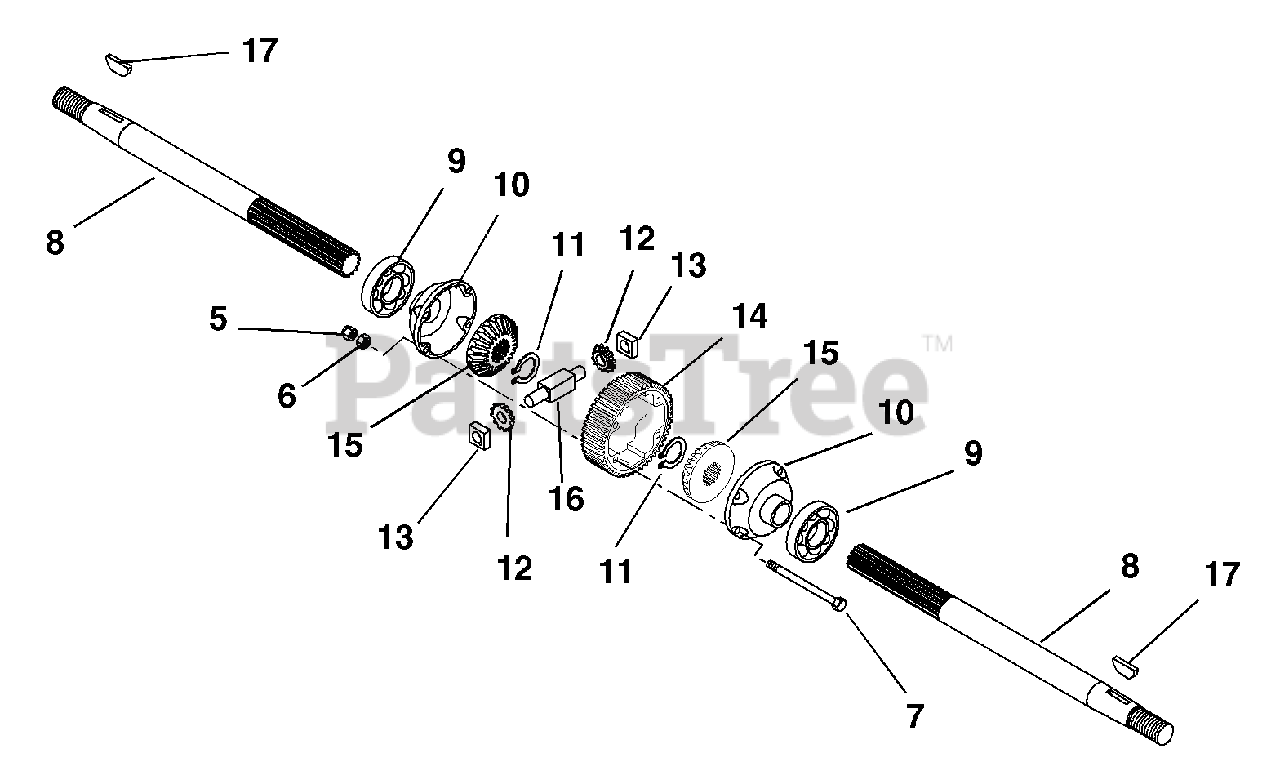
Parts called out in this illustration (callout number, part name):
5	Nut-Locking-Center .31-18
6	Nut-Hex .31-18 Grade 8
7	Bolt-Hex .31-18 x 2.75 Grade 8
8	Axle, Bevel Gear Differential
9	Bearing-Ball 1.57 x 2.68 x .59
10	Cap, Differential End
11	Ring-Retaining-External 1.15 x .093
12	Pinion Bevel
13	Block, Drive
14	Gear, Final Drive
15	Gear, Bevel
16	Pin, Spider Pinion
17	Key-Woodruff .19 x .63
